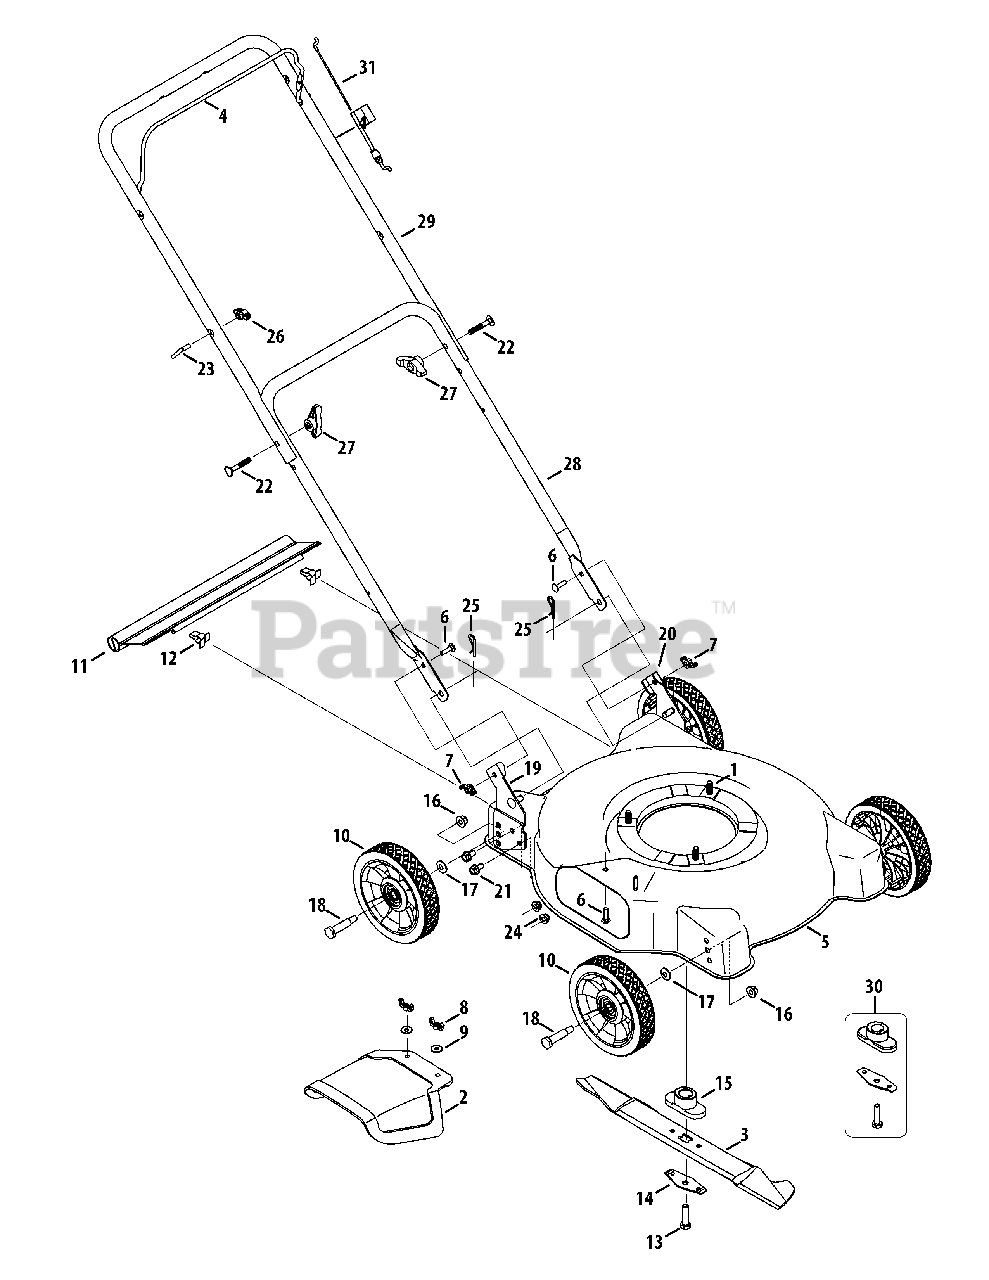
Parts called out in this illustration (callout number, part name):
1	Hex Ind. Washer Screw, 3/8-16 x 1.0
2	Discharge Chute
3	Cutting Blade
5	Cutting Deck, 20"
6	Carriage Screw, 1/4-20 x 1.0"
7	Wing Nut, 1/4-20
8	Wing Nut, 1/4-20
9	Flat Washer
10	Wheel, 7" Star-Dia., Oys. Gray
11	Rear Flap
12	Hinge Clip
13	Screw, 3/8-24 x 1.5"
14	Blade Bell Support
15	Blade Adapter
16	Flange Lock Nut, 3/8-16
17	Bell Washer
18	Shoulder Screw, .498 x 1.635
19	Handle Bracket Assembly, RH
20	Handle Bracket Assembly, LH
21	Hex Screw, 5/16-18 x .625"
22	Carriage Bolt, 5/16-18 x 2.0
23	Eye Bolt
24	Flange Lock Nut, 5/16-18
25	Click Pin, .092 x 1.64
26	Wing Nut
27	Wing Knob
29	Upper Handle
30	Blade Adapter Kit (Incl. Ref. 13-15)
31	Control Cable
